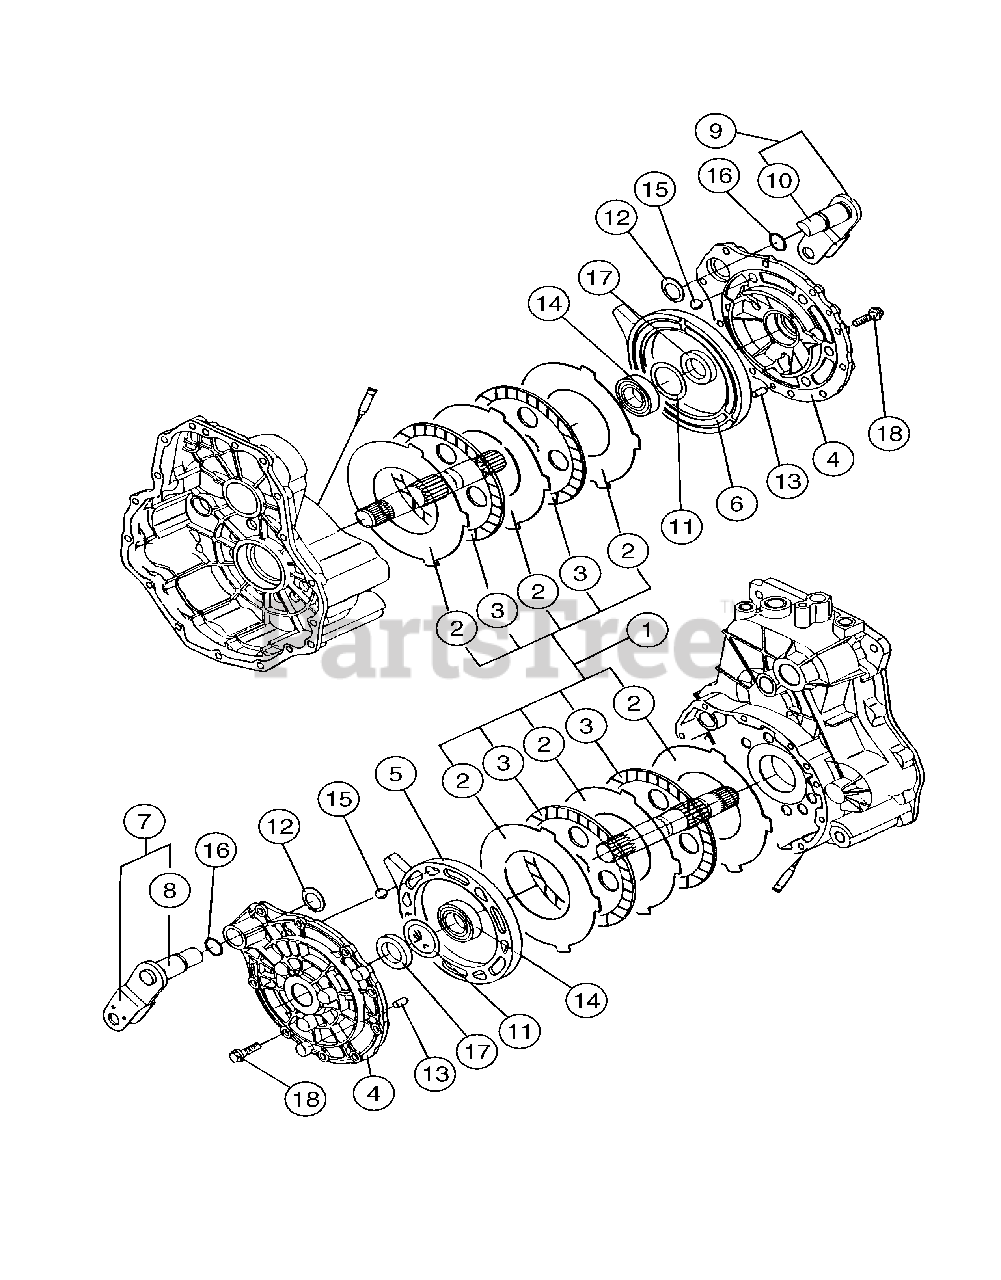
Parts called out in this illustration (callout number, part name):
2	Steel Plate
3	Friction Plate, 175
7	Cam Lever, Complete, LH
8	Cam Lever Shaft
9	Cam Lever, Complete, RH
10	Cam Lever Shaft
11	Washer, 42 x 54.6 x 1
14	Bearing, 6006
16	Packing, P 21
17	Seal, TC304708
18	Tapping Screw, 8 x 30
18	Flange Bolt, M8 x 30
